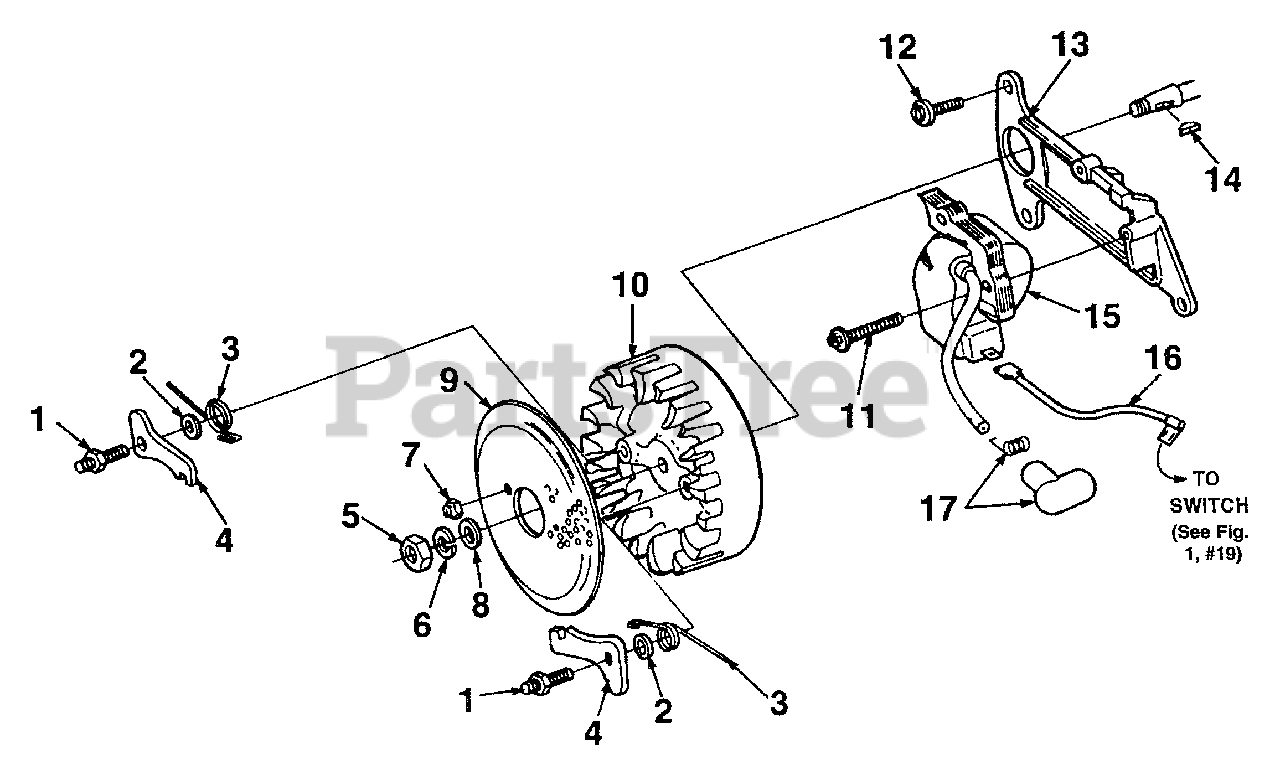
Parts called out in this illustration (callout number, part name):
1	STUD-Shoulder
2	WASHER-Lock
3	SPRING-Starter Pawl
4	PAWL-Starter
5	NUT-Hex (5J/16-24)
6	WASHER-Lock (5/16)
7	NUT-Center Lock (#10-32)
8	WASHER-Flat (5/16)
9	SCREEN-Starter
10	ROTOR-Magneto
11	SCREW-Hex Washer Hd. (8-32 X 3/4)
12	SCREW-Hex Hd. (12-24 X 9/16)
13	PLATE-Ignition Coil Mtg. (Solid State)
14	KEY-Woodruff
15	MODULE & CORE
16	LEAD-Ground (Solid State)
17	TERMINAL-High Tension
